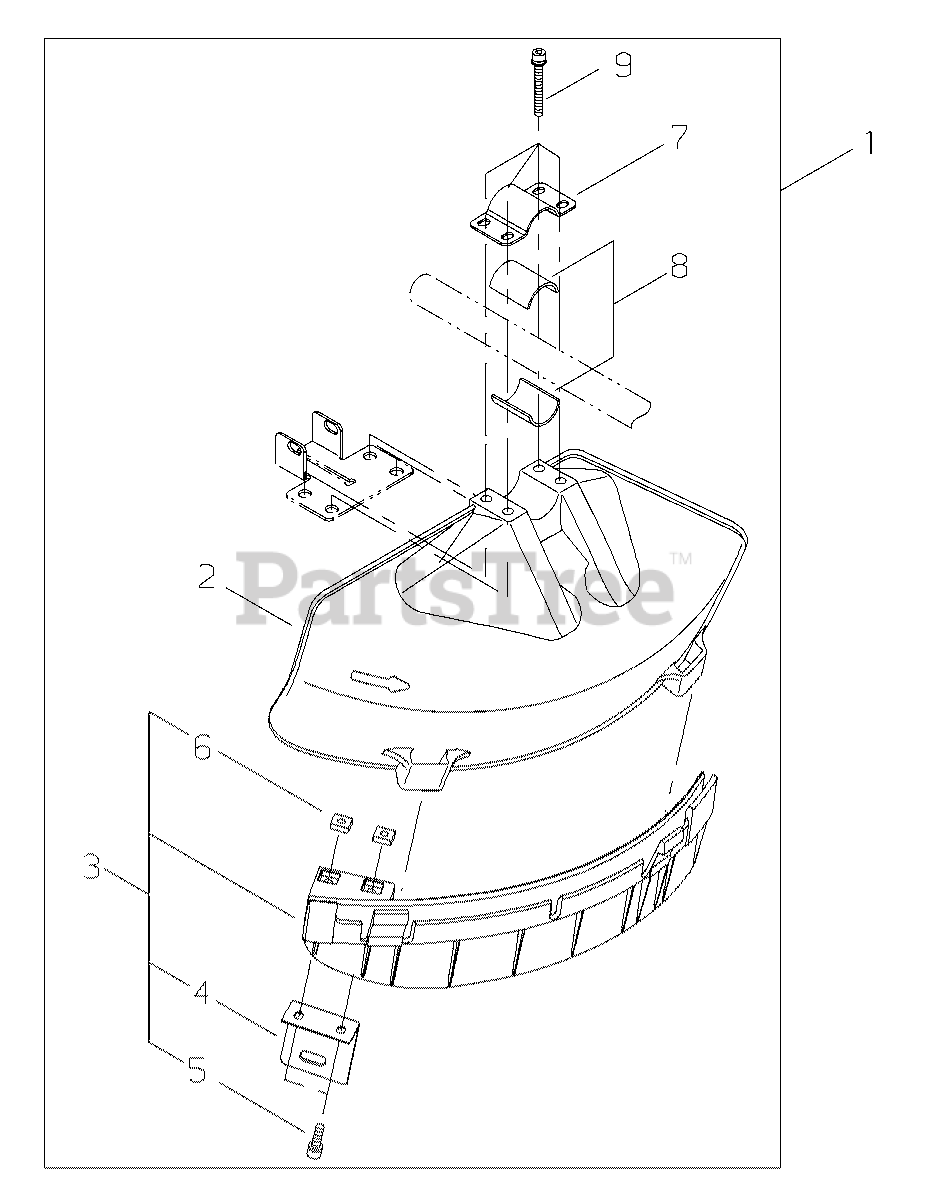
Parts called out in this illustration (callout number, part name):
1	DEBRIS SHIELD KIT
2	SHIELD, DEBRIS PLASTIC
3	DEBRIS SHIELD EXTENSION ASSY
4	CUTTER
5	BOLT M5×16
6	NUT M5
7	CLAMP, UPPER
8	SPACER
9	BOLT M5×45
